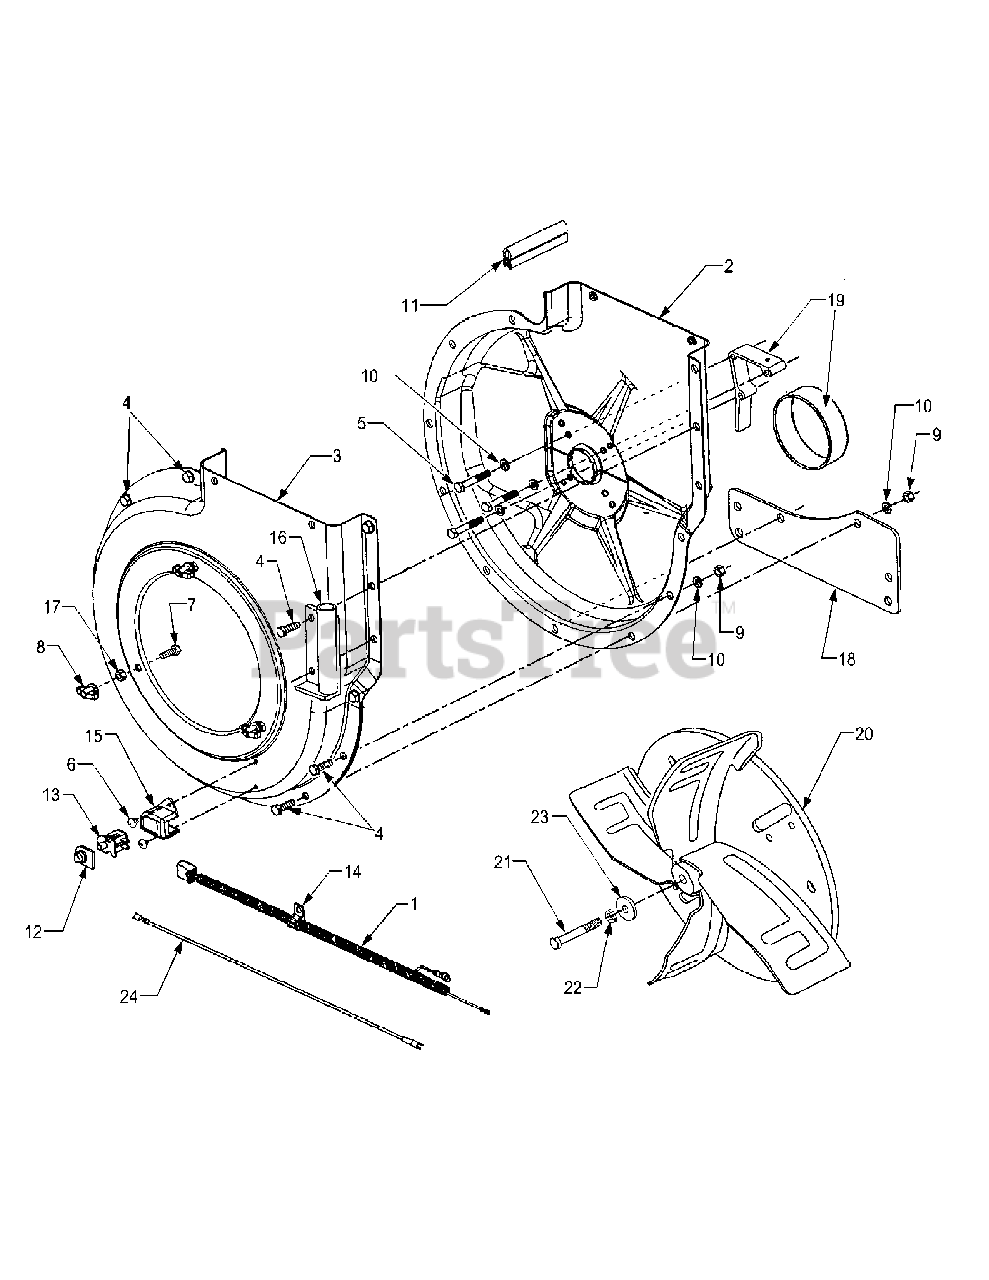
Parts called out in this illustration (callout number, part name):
1	Harness,Wire
2	Housing Ass'y.Inner
3	Housing Ass'y.Outer
4	Bolt,Hex 5/16-18 x 3/4"
5	Bolt,Hex 5/16-24 x 2"
6	Screw,Self Tap #10-16 x 3/8"
7	Bolt,Hex 5/16-18 x 1"
9	Nut,Hex Lock 5/16-18
10	Washer,Lock 5/16"Spring Type
11	Seal,Rubber
12	Cover,Switch
13	Snap Mount Switch
15	Cover,Switch
16	Hose Hanger Bracket.Ass'y
17	Nut,Hex Jam 5/16-18 Thd
18	Spacer,Housing
19	Adapter,Mounting
20	Impeller Assembly
21	Bolt,Hex 3/8-24 x 2-3/4"
22	Lockwasher,3/8"
23	Flat Washer,13/32"x 1-1/4"
24	Harness Adapter
